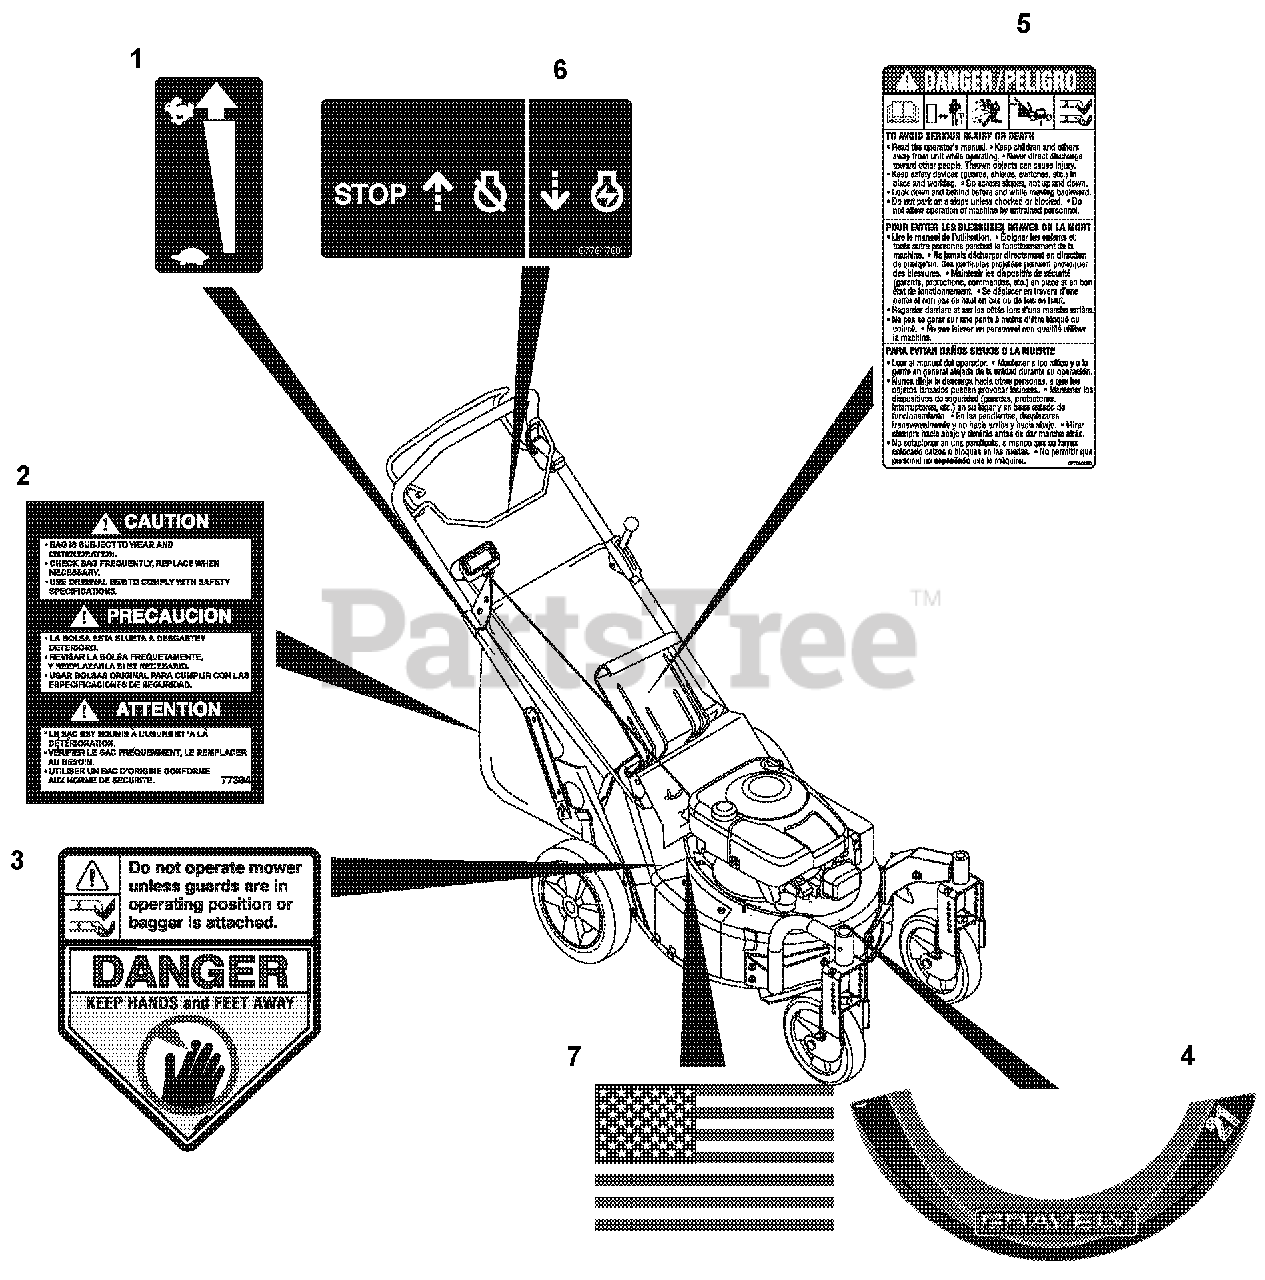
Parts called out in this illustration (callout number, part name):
1	Decal, Speed Control
2	Label, Bagger 21"
3	Decal, CPSC Danger
4	Decal, Gravely Deck
5	Decal, Bilingual Danger
6	Decal, Engine Control
7	Decal, American Flag
